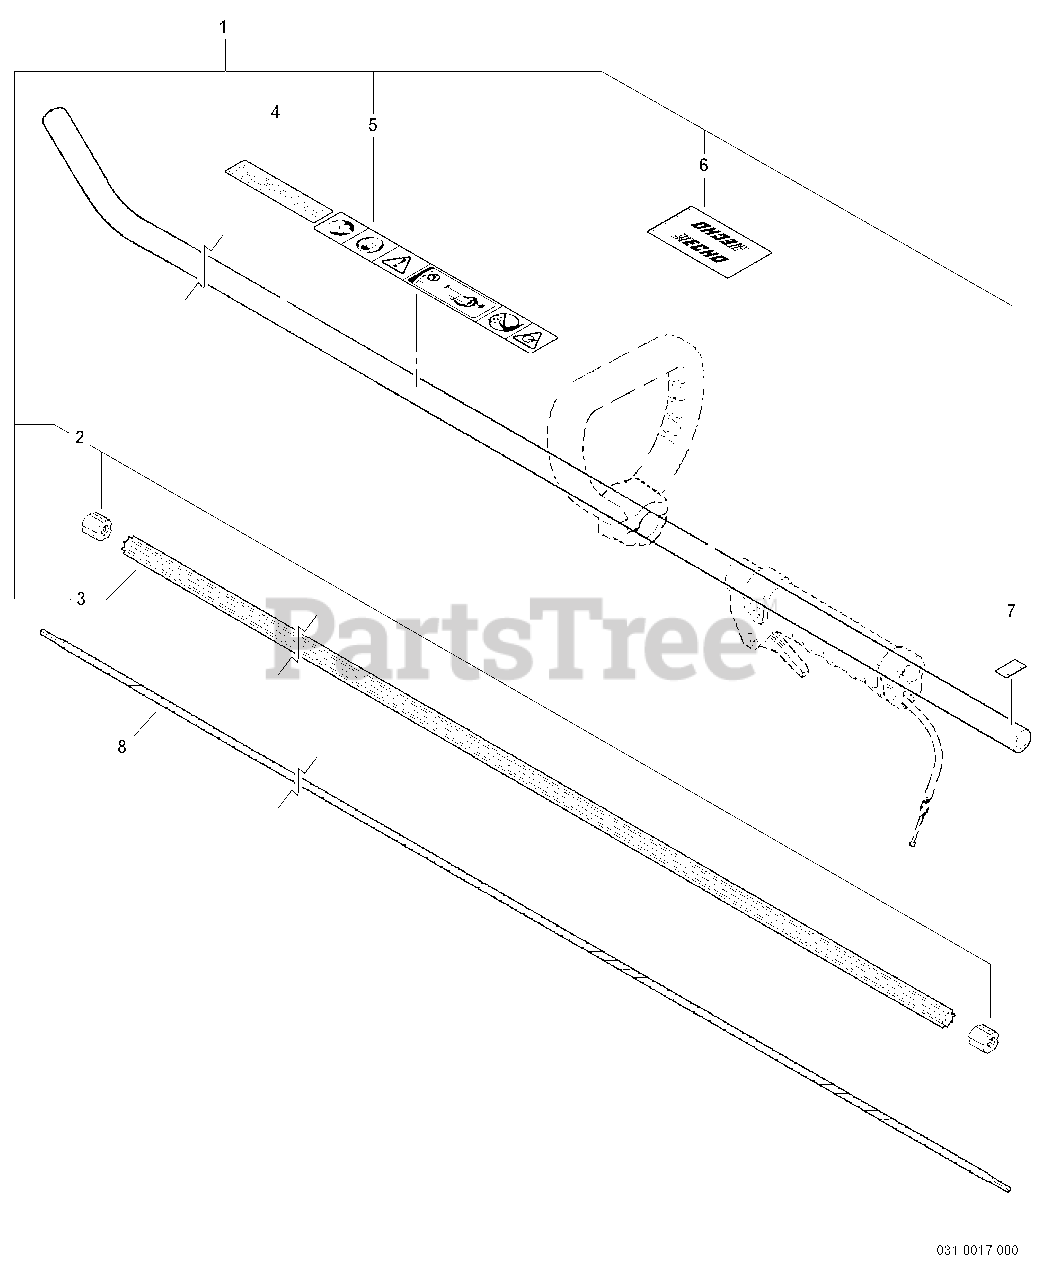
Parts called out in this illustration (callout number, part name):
1	MAIN PIPE ASSY
3	LINER - FLEXIBLE
4	LABEL - CAUTION -- SPANISH
5	LABEL - CAUTION
6	LABEL - HANDLE LOCATION
7	LABEL - ALIGNMENT
8	DRIVESHAFT - FLEXIBLE
